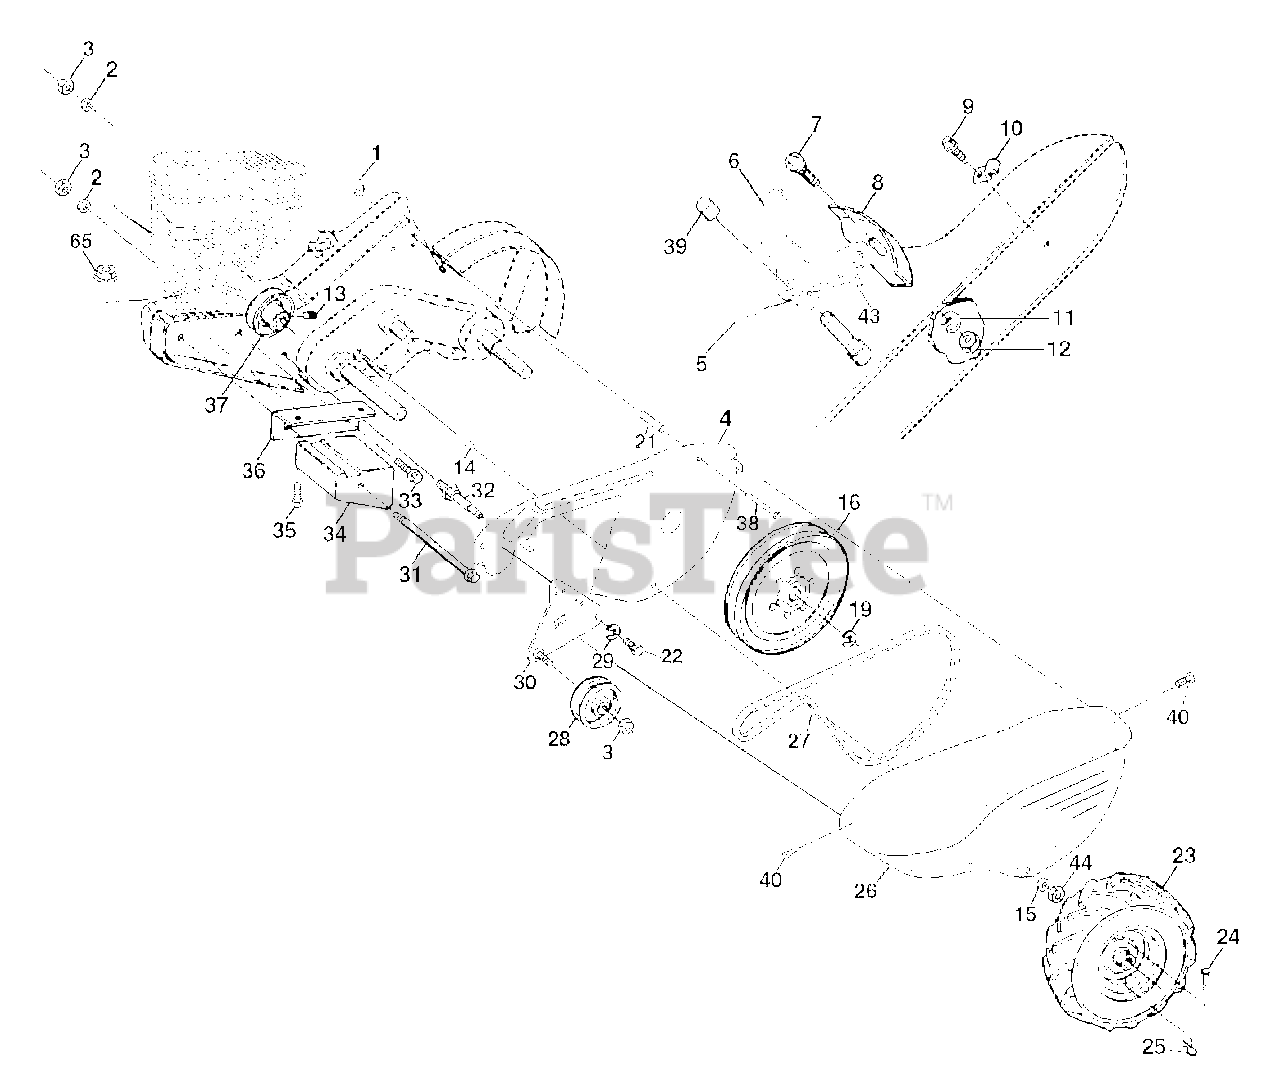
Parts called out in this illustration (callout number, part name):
1	Nut, Keps 5/16-18
2	Washer, Lock 3/8
3	Nut, Hex 3/8-16
4	Shield, Inner Belt Guard RT
5	Screw, Shift Lever
6	Lever, Shift
7	Bolt, Carriage 1/4-20 x 1/2 Gr. 5
8	Plate, Shift Indicator
9	Screw, Hex, Washer Head, Slotted #10-24 x 1/2
11	Washer, Lock 1/4
12	Nut, Hex 1/4-20
13	Screw, Set, Hex 5/16-18 x 3/8
14	Spacer, Split 0.327 x 0.42 x 2.09
15	Washer 11/32 x 11/16 x 16 Ga.
16	Sheave, Transmission
19	Retainer, Ring
21	Spacer, Split
22	Bolt, Fin Hex 5/16-24 UNF x 1/2
23	Rim
23	Tire Valve
24	Rivet, Drilled
25	Clip, Hairpin
26	Guard, Belt
27	Belt, V
28	Pulley, Idler
29	Ring, Klip
30	Bracket, Idler
31	Bolt, Hex 5/16-16 x 12
32	Shaft, Idler Arm
33	Bolt, Hex 3/8-16 x 1
34	Counterweight, L. H.
35	Bolt, Hex 5/16-18 x 2
36	Bracket, Reinforcement, L. H.
37	Sheave, Engine
38	Bolt, Fin Hex 5/16-18 UNC x 2-3/4
39	Cap, Plunger Blk
40	Screw Hex Wsh Slt #10-24 x 1/2
43	Nut, Lock #10-24
44	Nut Lock Hex w/Ins 5/16-18 Unc PL
65	Nut Lock Hex Flange
